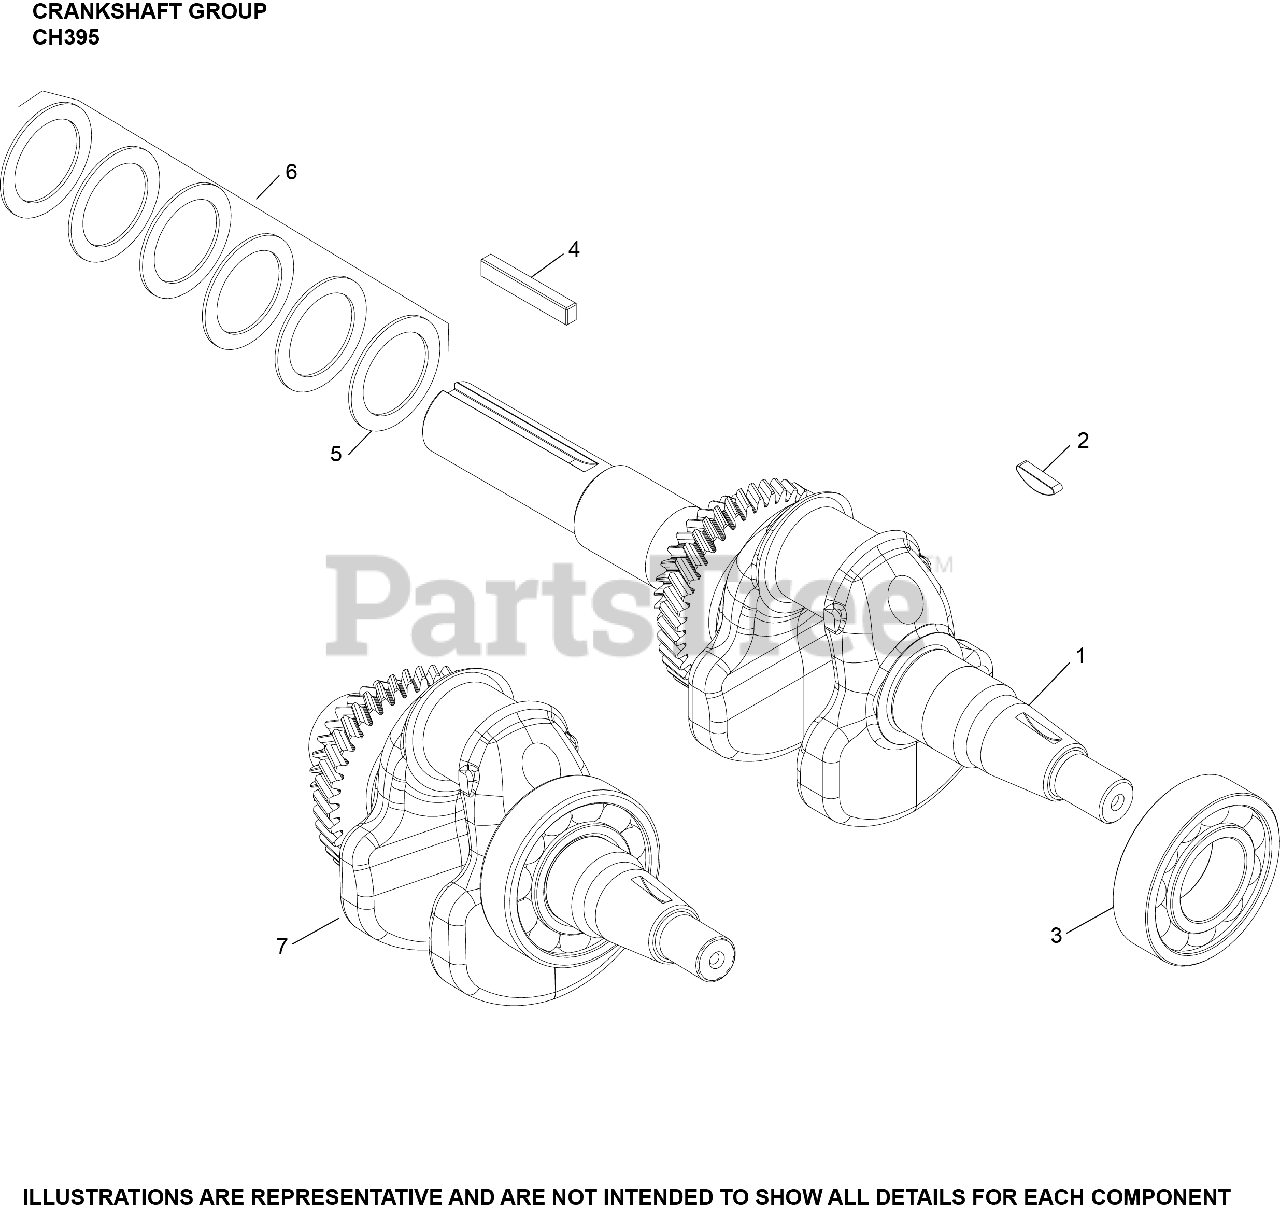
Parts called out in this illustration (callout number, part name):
1	CRANKSHAFT ASSEMBLY
2	KEY, FLYWHEEL
4	KEY, SQUARE
6	KIT, SHIMS
